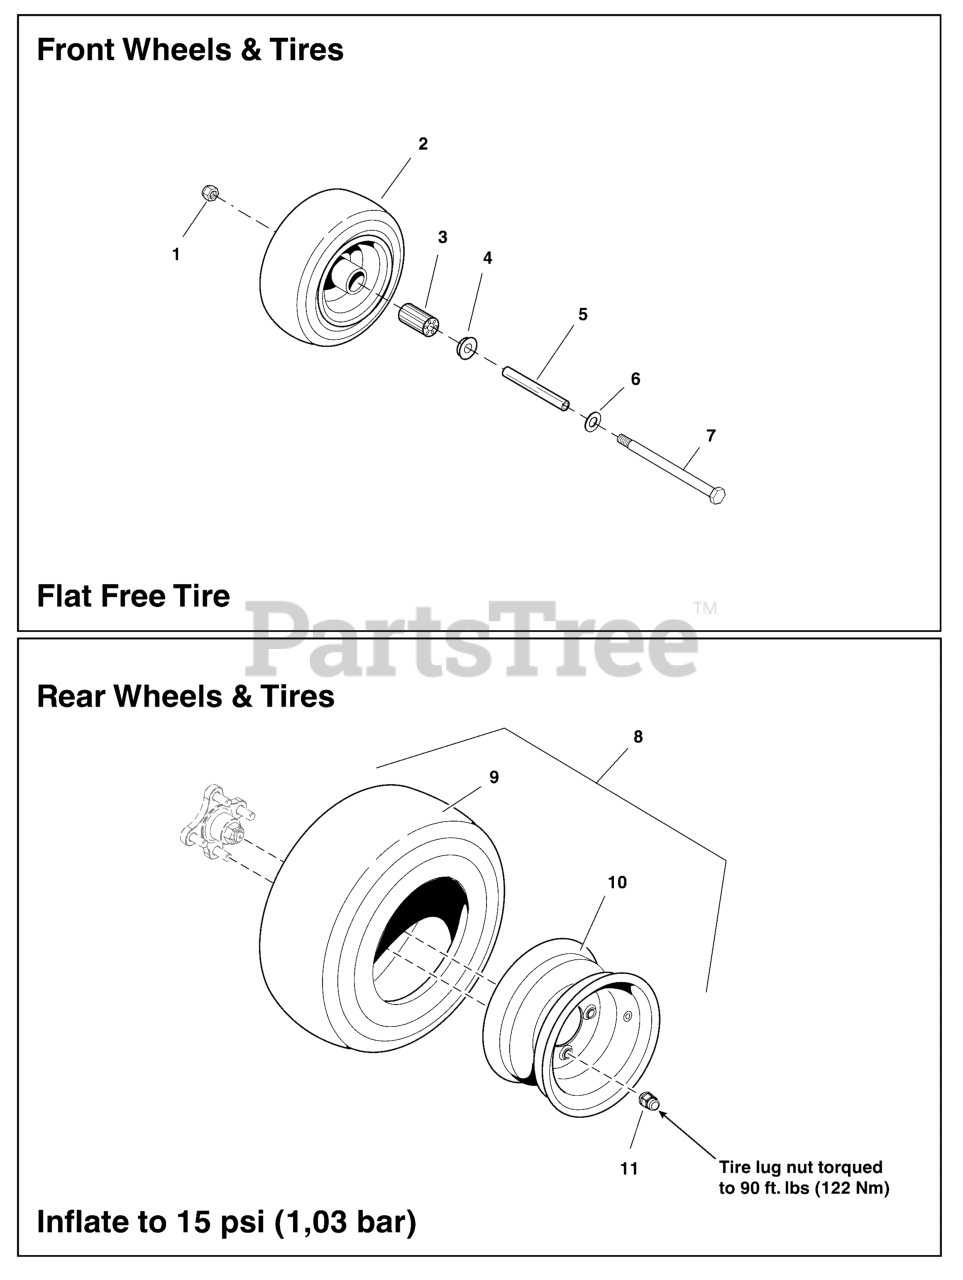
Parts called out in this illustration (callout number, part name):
1	NUT, Hex Flange, Nylock, 1/2-13
2	TIRE ASM, 9 X 3.5-4 FF/CB, BLK
3	BEARING, ROLLER 3/4" ID X 3.25" (ONE PER TIRE)(SV)
4	RETAINER, BEARING
5	AXLE, CASTER WHEEL
6	WASHER, 1/2 SAE
7	BOLT, 1/2-13 X 6 GD5 CZ
8	TIRE ASM, 20 X 7 - 10, TURF, 4 BOLT, BLK
9	TIRE, 20X7.00-10NHS, TURF MASTER
10	WHEEL RIM
11	NUT
11	NUT, 1/2-20, FOR WHEEL BOLT SILVER
